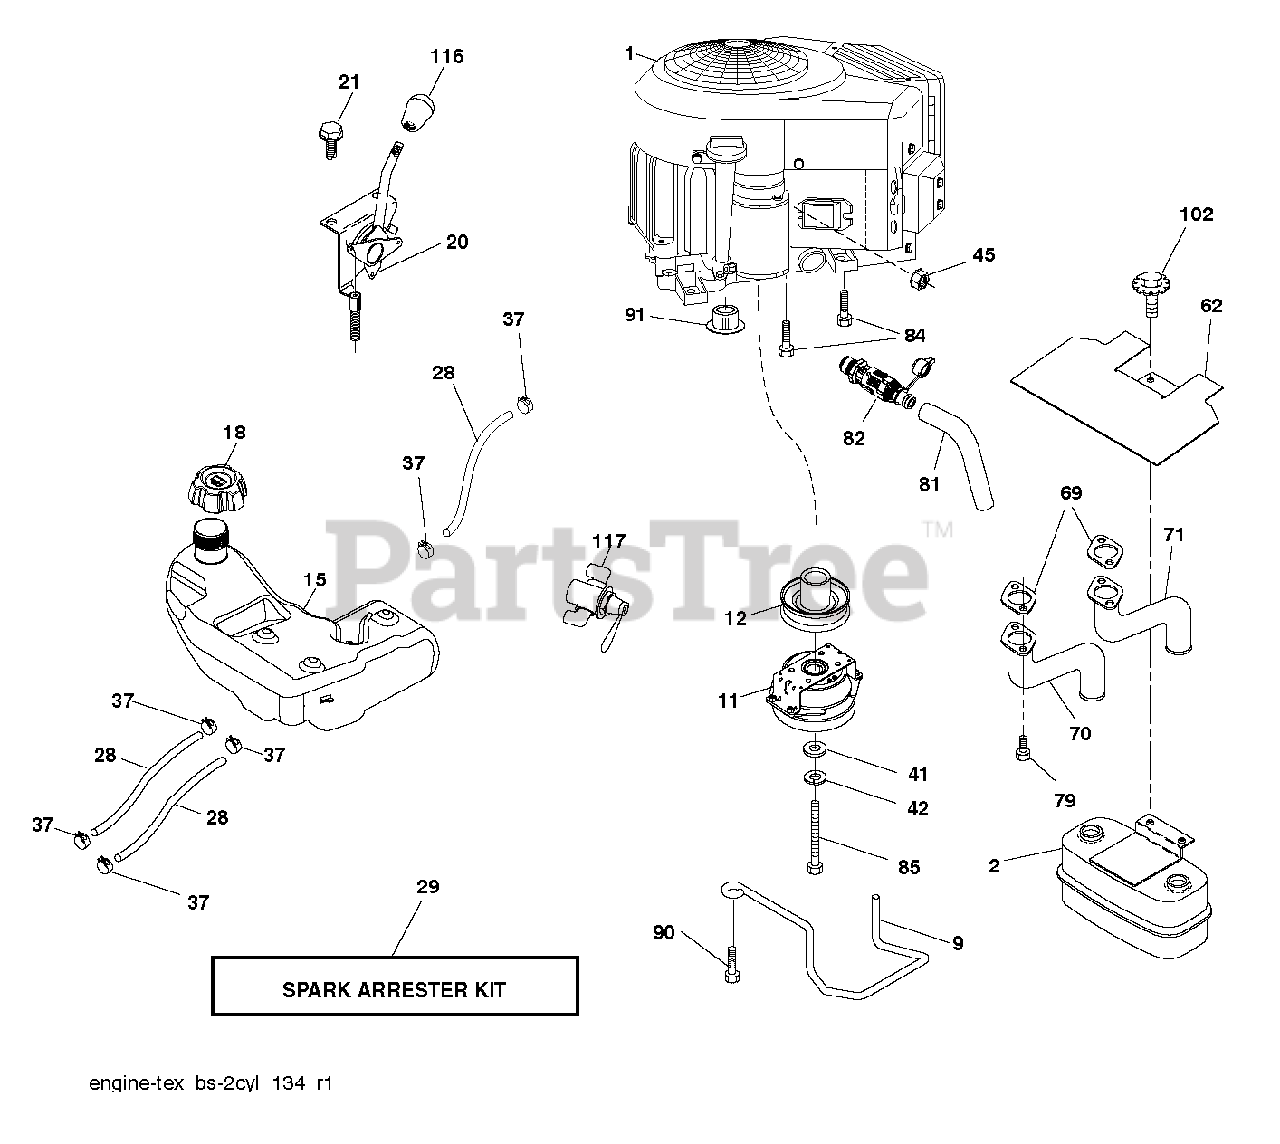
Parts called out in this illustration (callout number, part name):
2	MUFFLER.ASM.TWN.EXTNDED.DFLCTR
9	KEEPER BELT ENGINE
11	CLUTCH.OGURA.5.0PD.GT1.5A-EH01
12	PULLEY ENGINE
15	TANK.ASSY.4.GAL.2.PORT.EPA
18	CAP ASSY FUEL 3" GRAY
20	THROTTLE.PRO.RSTART. 38
21	SCREW.#10 X 0.750.BOS
28	LINE.FUEL.64"REAR.EMIS
29	KIT.SPARK ARRESTOR 794945 B&S
37	HOSE CLAMP
42	LOCKWASHER
45	NUT
62	SHIELD.HEAT.MUFFLER
69	GASKET.MUFFLER
70	EXHAUST.TUBE.LH.BS/TWIN
71	EXHAUST.TUBE.RH.B&S.TWIN.INTEK
79	SCREW.SOCKET.HEAD.5/16-18
81	TUBE, DRAIN OIL ASM.
82	VALUE.OIL.DRAIN
84	SCREW.3/8-16
85	BOLT.HEX.7/16-20X3.0XGR5
90	SCREW 3/8-16X1
91	BUSHING.1.375OD
102	SCREW
116	KNOB - SHIFT
117	VALVE FUEL RESERVE
